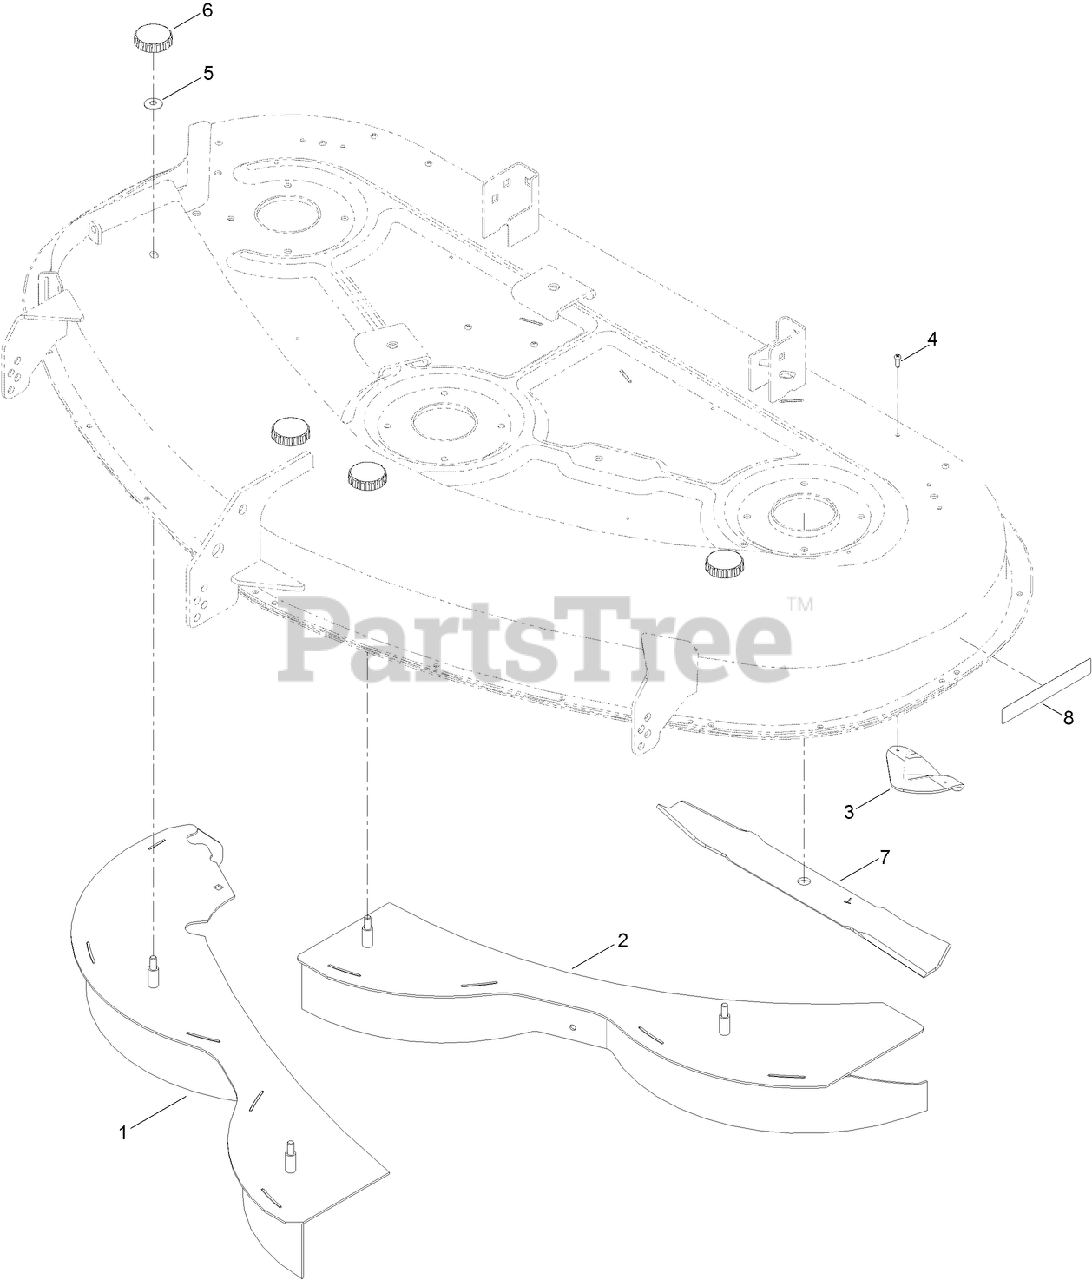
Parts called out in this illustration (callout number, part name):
1	RH BAFFLE ASM
2	LH BAFFLE ASM
3	PLATE-KICKER
4	SCREW-PPH
5	WASHER-BELLEVILLE
7	BLADE-MULCH, 18.75 INCH
8	DECAL-RECYCLER
